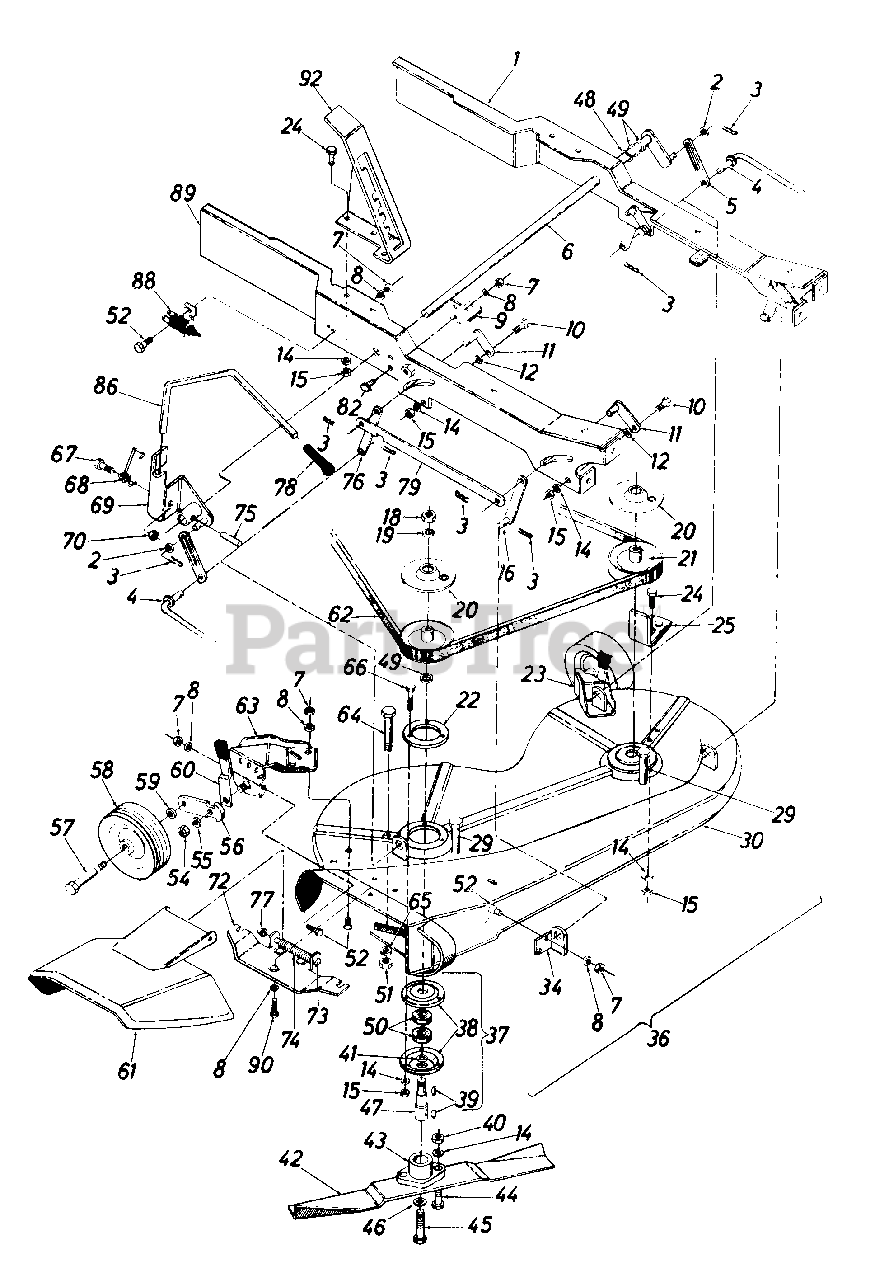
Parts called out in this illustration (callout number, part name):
1	Side Rail Ass'y. - L.H.
2	Flat Washer .531 I.D. x .930 O.D. x .090
3	Internal Cotter Pin for 3/8" Dia.
4	Stabilizer Rod
5	Slotted Link
6	Lift Shaft Ass'y.
7	Hex Nut 1/4-20 Thd.
8	Spring Lock Washer 1/4" Scr.
9	Blade Brake Ass'y.
10	Shld. Scr. .437" Dia. x .180
11	Pivot Link Ass'y.
12	Flat Washer .344 I.D. x .62" O.D.
14	Spring Lock Washer 5/16"
15	Hex Nut 5/16-18 Thd.
16	Deck Link Ass'y.
18	Hex Jam L-Nut 5/8-11 Thd.
19	Spring Lock Washer 5/8" Scr.
20	Brake Disc Ass'y.
21	Deck Pulley
22	Reinforcement Plate
23	Wheel Bracket Ass'y. - L.H.
24	Hex Sems Scr. 5/16-18 x .75"
25	Belt Keeper Ass'y.
29	Shld. Scr. .498" Dia. x 2.00"
30	Deck Ass'y.
34	Deck Bracket
36	34 Inch Deck Ass'y. - Comp.
37	Blade Spindle Ass'y. - Comp.
38	Bearing Cup
39	#6 Hi-Pro-Key 5/32 x 5/8"
40	Hex Nut 5/16-24 Thd.
41	Fl-Wash. .793 I.D. x 1.24 O.D.
42	17 Inch Blade
43	Blade Adapter Kit
44	Hex Scr. 5/16-24 x 1.00" Lg.
45	Hex Scr. 3/8-24 x 1.50" Lg.
46	Spring Lock Washer 3/8" Scr.
47	Blade Spindle
48	Wave Washer .62" I.D.
49	Flat Washer .635 I.D. x .930
50	Ball Bearing
51	Hex Nut 3/8-16 Thd.
52	Hex Scr. 1/4-20 x .50" Lg.
54	Hex Inserted Lock Nut 3/8-24
55	Belleville Washer .40" I.D. x 1.13 O.D. x .030
56	Wheel Pivot Bar
57	Shld. Scr. 5/8" Dia. x 1.75"
58	5" Wheel Ass'y.
59	Belleville Washer .400 I.D. x .88" O.D. x .060
60	Spring Lever Ass'y. w/knob
61	Chute Cover Ass'y. - Comp.
62	"V"-Belt 21/32 x 82" Lg.
63	Wheel Bracket Ass'y. - R.H.
64	Shld. Scr. .498" Dia. x 1.450" Lg.
65	Spring Lock Washer 3/8" Scr.
66	Hex Sems Scr. 5/16-18 x 1.00"
67	Hex Scr. 1/4-20 x 1.50" Lg.
68	Torsion Spring
69	Handle Bracket Ass'y.
70	Hex Center Lock Nut 1/4-20
72	Adapter Ass'y.
73	Hinge Pin
74	Torsion Spring
75	Spring Pin 5/16" Dia. x 1.38"
76	Deck Link
77	Push Nut 1/4" Rod
79	Connecting Rod
82	Carriage Bolt 1/4-20 x .62"
86	Lift Handle
88	Safety Switch (Lift)
89	Side Rail Ass'y. - R.H.
90	Hex Scr. 1/4-28 x .62" Lg.
92	Index Bracket
